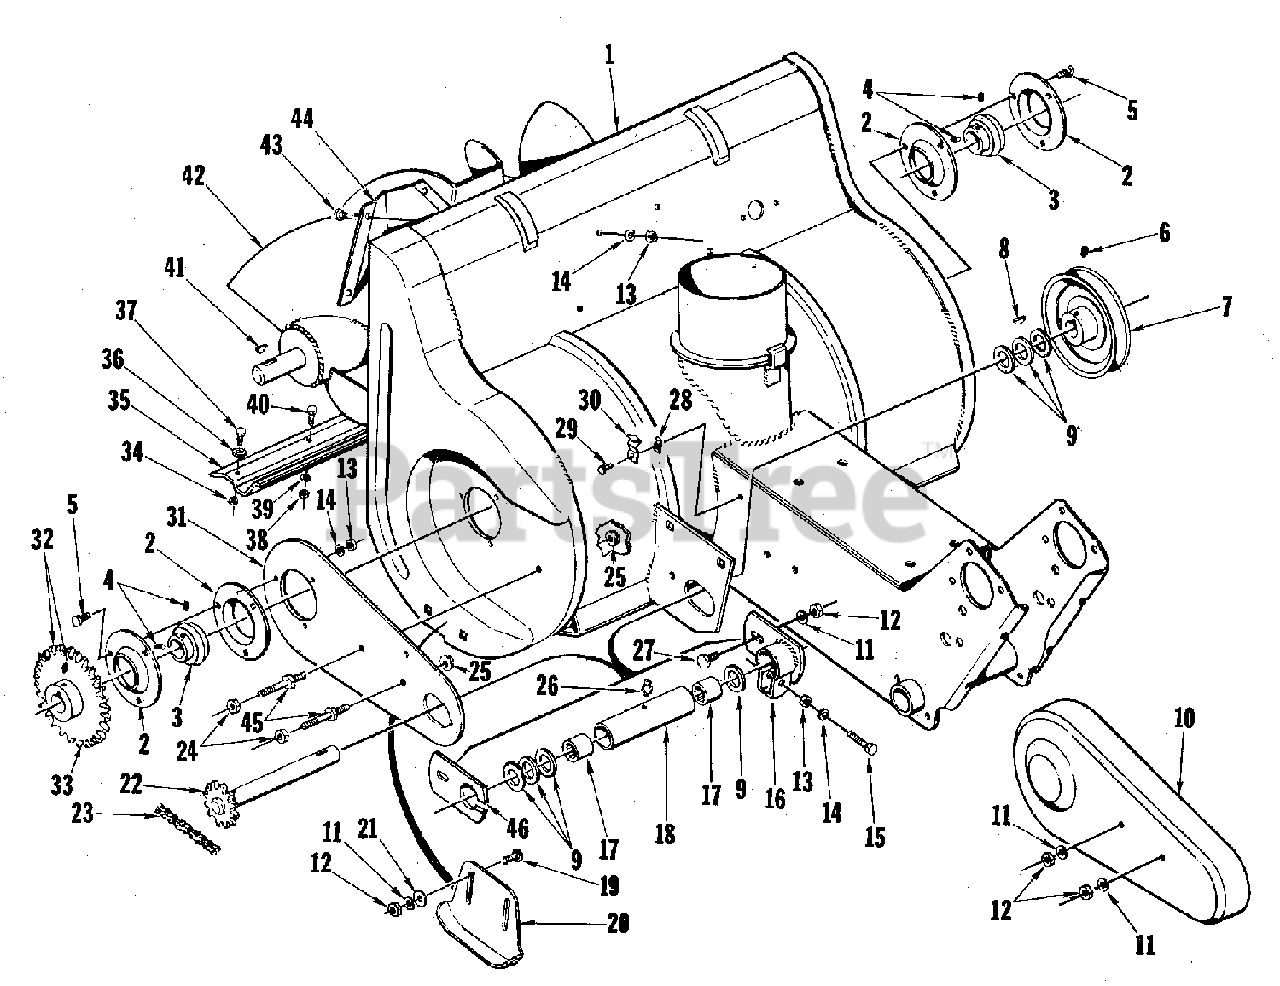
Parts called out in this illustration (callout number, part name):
1	BODY, Frame Assembly
2	FLANGE, Bearing
3	CARTRIDGE, Bearing
4	SCREW, Set, 1/4-28 x 1/4
5	SCREW, Hex, 5/16-18 x 3/4
6	SCREW, Set, 5/16-18 x 5/16
10	GUARD, Chain
11	WASHER, Lock, 3/8"
12	NUT, Hex, 3/8-16
13	NUT, Hex, 5/16-18
14	WASHER, Lock, 5/16"
15	SCREW, Hex Head, 5/16-18 x 1-1/2
16	CLAMP, Housing
17	BEARING, Needle
18	HOUSING, Bearing
19	BOLT, Carriage, 3/8-16 x 3/4
21	WASHER, Flat
22	SHAFT ASSEMBLY
24	NUT, Hex, 3/8-16
25	NUT, Flange, Whiz Lock, 3/8-16
26	FITTING, Grease
27	SCREW, Hex, 3/8-16 x 1
28	NUT, Tinnerman
29	SCREW, Self Tapping, #10 x 1/2
32	SCREW, Set, 5/16-18 x 5/16
33	SPROCKET, Rotor
34	NUT, Hex, 5/16-18
35	SCRAPER, Body
36	WASHER, Plain, 1/4"
37	SCREW, Hex, 5/16-18 x 5/8
38	NUT, Hex, 1/4-20
39	WASHER, Lock, 1/4
40	SCREW, Hex, Head, 1/4-20 x 5/8
42	ROTOR ASSEMBLY
43	SCREW, Hex Head, 5/16-18 x 5/8
